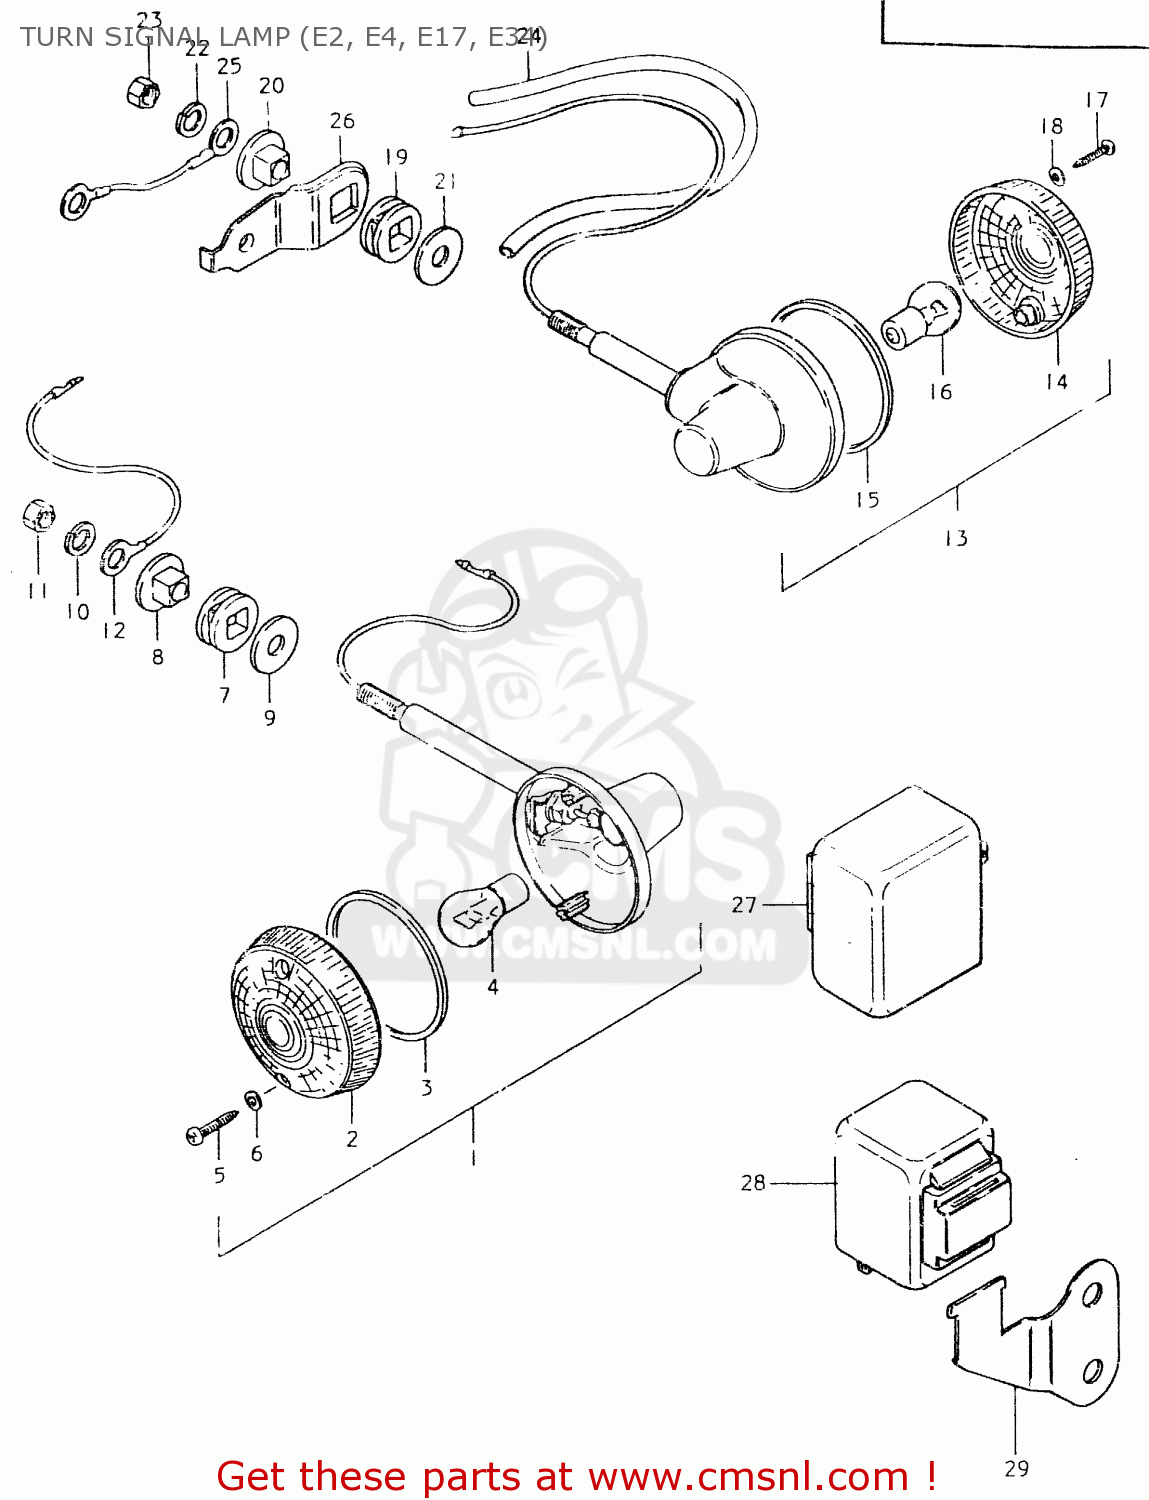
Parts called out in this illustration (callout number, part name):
1	LAMP ASSY, FRONT TURN SIGNAL
2	LENS
3	GASKET (NAS)
4	BULB (6V,21W)
5	SCREW
6	GASKET (NAS)
7	CUSHION
8	SPACER,TURN SIGNAL LAMP
9	WASHER (10.5X30X2.3)
10	LOCK WASHER
11	NUT
12	LEAD WIRE,EARTH
13	LAMP ASSY, REAR TURN SIGNAL
14	LENS
15	GASKET (NAS)
16	BULB (6V,21W)
17	SCREW
18	GASKET (NAS)
19	CUSHION
20	SPACER,TURN SIGNAL LAMP
21	WASHER (10.5X30X2.3)
22	LOCK WASHER
23	NUT
24	PROTECTOR, LEAD WIRE
25	LEAD WIRE,EARTH
26	BRACKET,REAR TURN SIGNAL
27	RELAY, TURN SIGNAL
28	RELAY, TURN SIGNAL
29	BRACKET, RELAY
